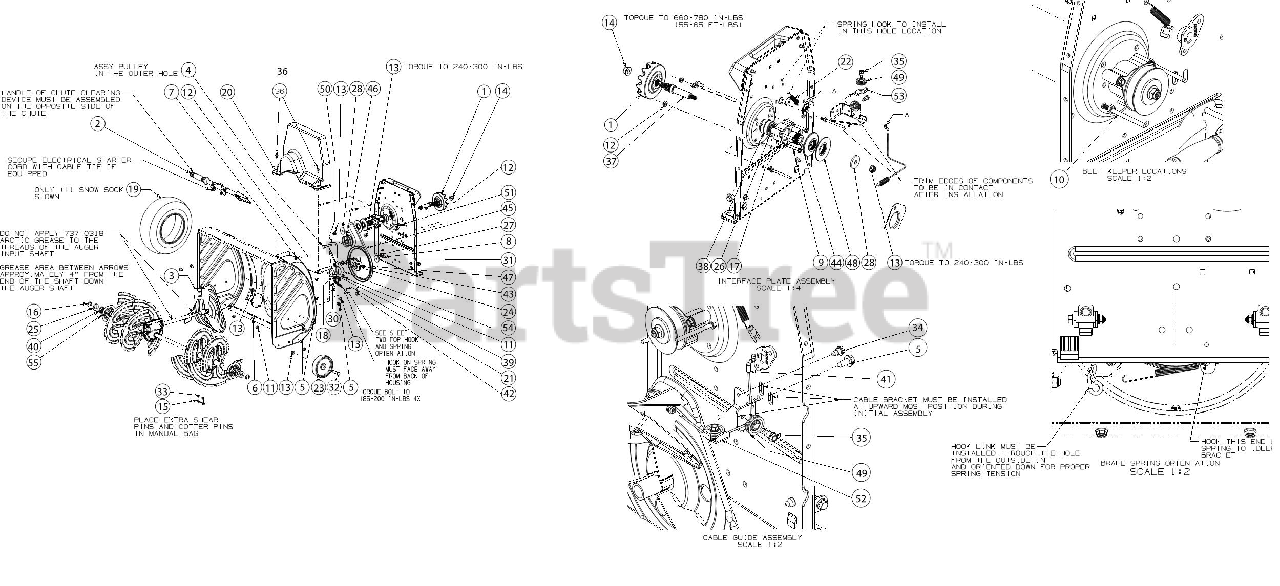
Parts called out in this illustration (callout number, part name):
1	DOG CLUTCH ASSEMBLY
1	DOG CLUTCH
1	DOG CLUTCH BUMPER
2	CLEANOUT TOOL MOUNTING CLIP
2	CLEANOUT TOOL
3	IMPELLER ASSEMBLY-12"
4	HEX SCREW 3/8-16 x 1.75 GR5
5	SCREW 5/16-18 x .750
6	CARRIAGE BOLT 5/16-18 x .75
7	SCREW 1/4-20 x .75 GR5
8	SCREW 5/16-24 x .875 GR5
9	SCREW 1/4-20 X1.625
10	BELT KEEPER .25X2.64
11	FLANGE LOCK NUT 5/16-18
12	FLANGE LOCK NUT
15	BOW TIE COTTER PIN 1/4-5/16
16	E-RING
17	BEARING CUP
18	PUSH ON NUT
19	SNOW SOCK 13" x 4"
20	SNOW COVER HOUSING
21	EXTENSION SPRING .38 OD x 4.59
22	EXTENSION SPRING
23	PLASTIC WHEEL 5X1.38
24	WAVE WASHER .660 ID X.88 OD x .010
25	FLAT WASHER .760ID X1.49OD x .06
26	SHIM WASHER
27	FLAT WASHER
28	FLAT WASHER .45 x 1.5 x .172 HT
29	ARCTIC GREASE (NOT SERVICEABLE)
30	SHOULDER SCREW .498 DIA x .340
31	SHOULDER SCREW .625
32	SHOULDER SCREW
33	SHEAR PIN .25 x 1.50 GR2
34	SHOULDER SCREW 1/4-20X.50 19"PSH
35	SHOULDER SCREW
36	TORX SHOULDER SCREW 1/4-20
37	DRIVE SPINDLE
38	BALL BEARING
39	FLANGE BEARING
40	FLANGE BEARING
41	AUGER CLUTCH CABLE
43	ADAPTER PULLEY .75 DIA W/DD
44	SPACER-.670ID x 1.185
45	BELT 34.50
46	IDLER PULLEY
47	AUGER PULLEY
48	HALF PULLEY 4L V x 2.6 OD
49	CABLE GUIDE ROLLER
50	IDLER BRACKET
51	CABLE FLEX BRACKET
52	CABLE BRACKET
53	CABLE GUIDE BRACKET
54	BEARING HOUSIN 1.85 ID
55	HEX BREARING HOUSING
